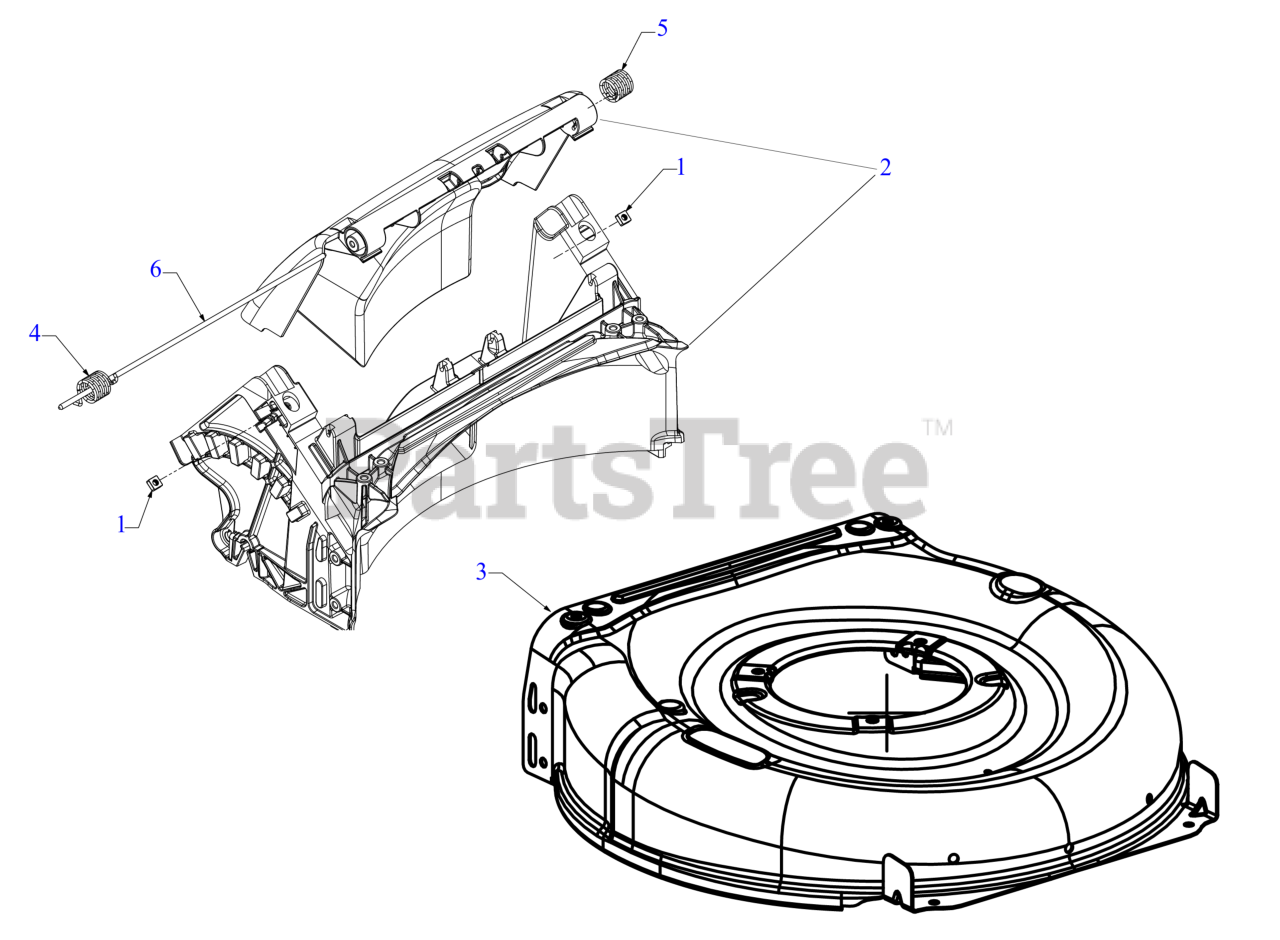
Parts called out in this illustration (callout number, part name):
1	SQUARE NUT 1/4-20
2	REAR DOOR ASSEMBLY
4	TORSION SPRING (RH)
5	TORSION SPRING (LH)
6	REAR DOOR PIVOT ROD
